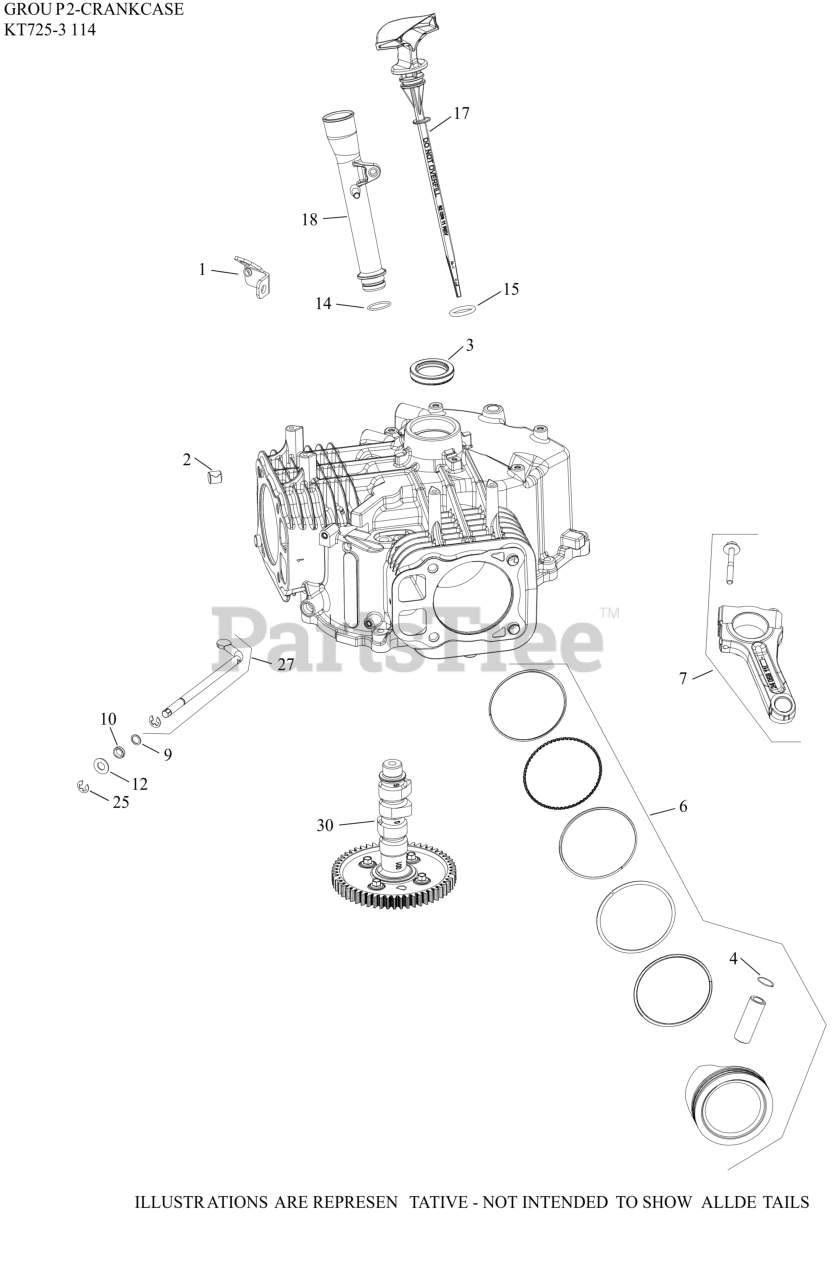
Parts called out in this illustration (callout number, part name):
1	BRACKET, OIL FILL TUBE
2	PIN, LOCATING
3	SEAL, OIL (HELIX LIP)
4	RETAINER, PISTON PIN
6	KIT, PISTON 725CC (STD) STYLE B
7	ROD, ASSEMBLY CONNECTING
9	WASHER, FLAT 11/32"
10	SEAL, GOVERNOR CROSS SHAFT
12	WASHER, FLAT 9 MM
17	DIPSTICK, ASSY
18	TUBE ASSEMBLY, OIL FILL
25	CLIP, RETAINER GOVERNOR SHAFT
27	KIT, CROSS SHAFT
30	CAMSHAFT ASSEMBLY
